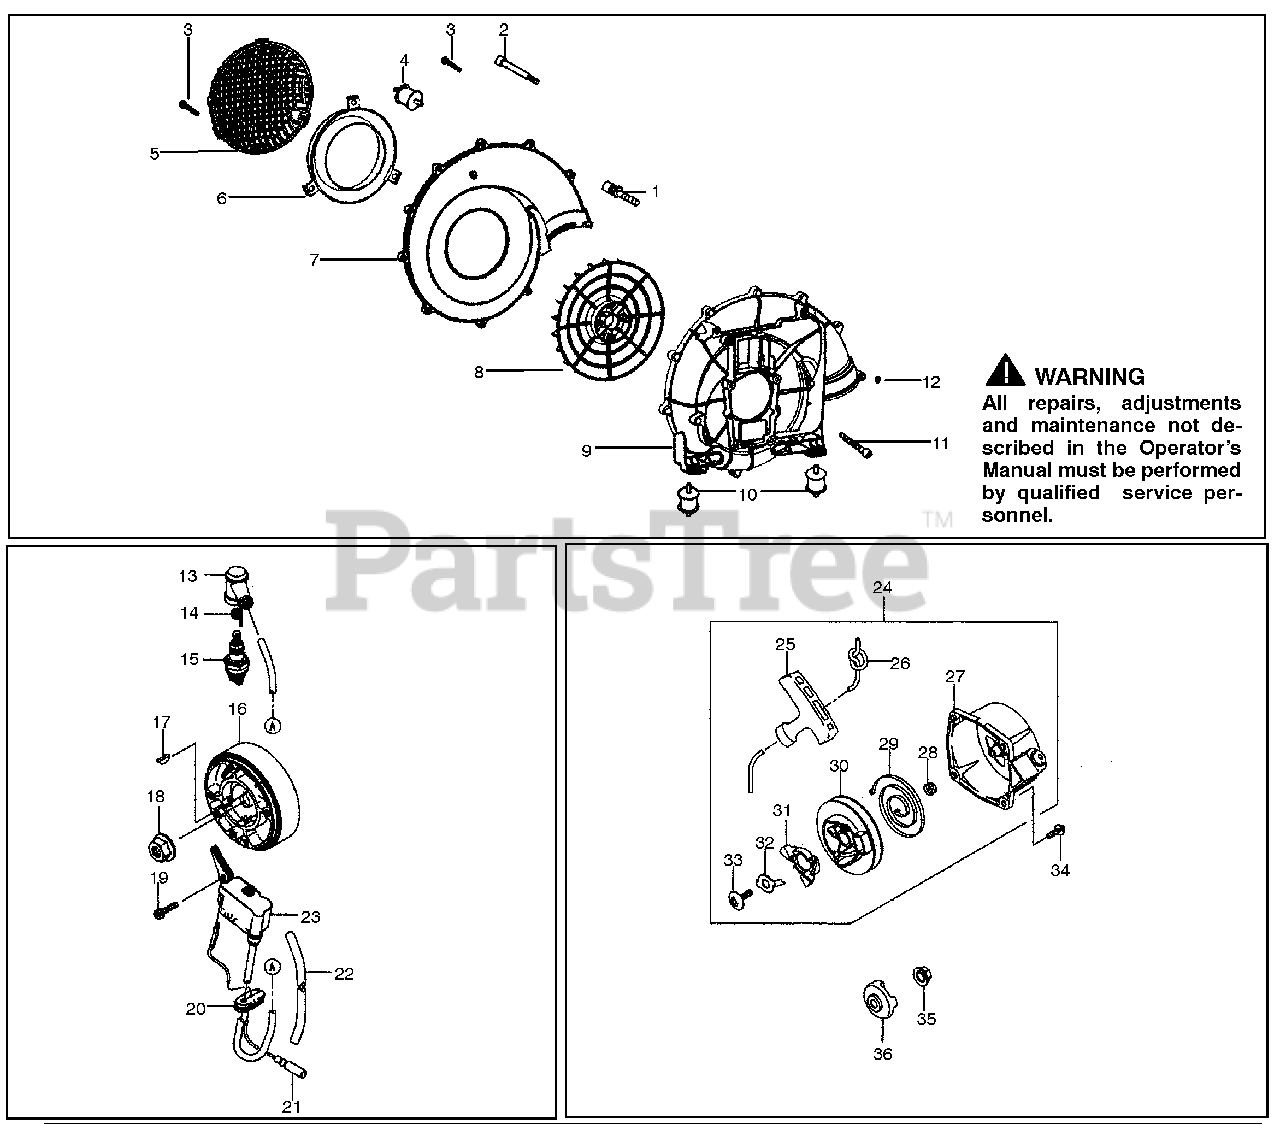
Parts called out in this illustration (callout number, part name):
1	Screw m5x25
2	Screw m5x65
3	Screw-Tapping m5x20
4	Vibro-Isolating rubber
5	Cover-Fan
7	Case-Fan
9	Case-Fan
10	Vibro-Isolating rubber
11	Screw m6x30
12	Nut-Nylon
13	Cap-Spark plug
14	Terminal
15	Plug-Spark (BPMR7A(NGK) Solid)
16	Flywheel
17	Key-Woodruff
19	Bolt m4x20
21	Wire-Lead
22	Tube 6x7.4x300
23	Assy-Ignition coil
24	Starter-Recoil
25	Grip-Starter Recoil
26	Rope-3.5x1000
27	Case-Starter Recoil
29	Spring-Recoil "A"
30	Reel-Starter Recoil
31	Pawl-Starter Recoil
32	Retainer
34	Screw m4x16
36	Pulley-Starting
